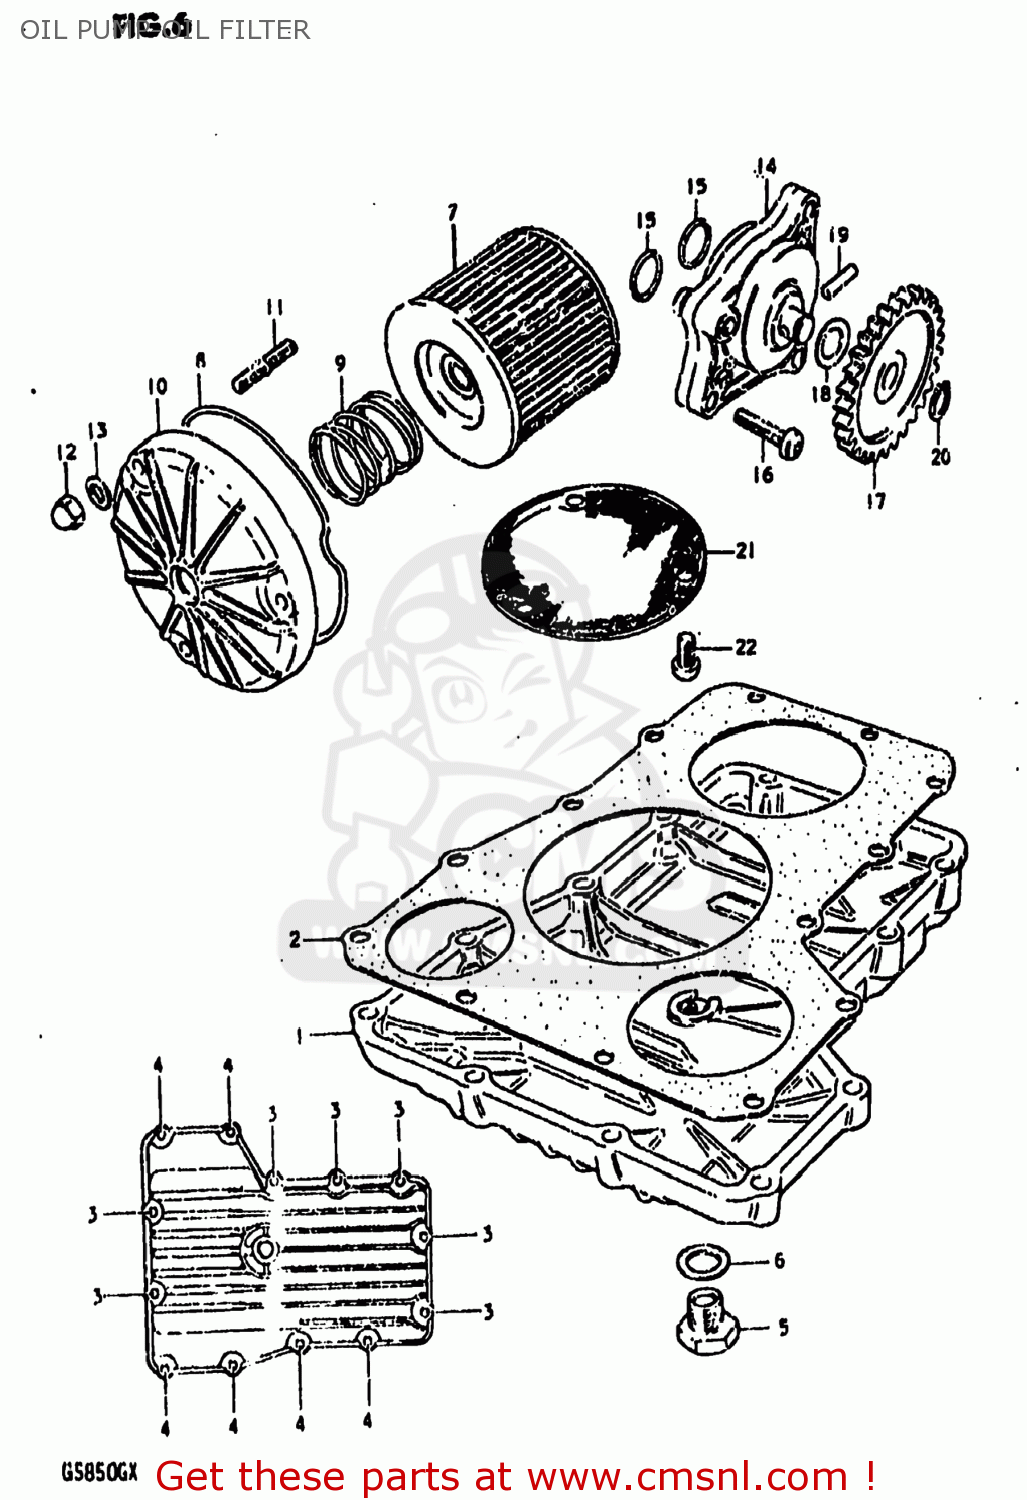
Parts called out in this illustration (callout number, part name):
1	PAN,OIL
2	GASKET,OIL PAN (MCA)
3	BOLT
4	BOLT
5	PLUG
6	GASKET(14X19.2X2) (NAS)
7	FILTER ASSY,ENGINE OIL
8	O RING,OIL FILTER CHAMBER CAP
9	SPRING
10	CAP,OIL FILTER
11	STUD 6X20
12	NUT
13	WASHER
14	PUMP ASSEMBLY,OIL
15	O RING(D:1.9,ID:13)
16	SCREW
17	GEAR,OIL PUMP DRIVEN
18	SHIM
19	PIN(4X15.8)
20	CIRCLIP
21	STRAINER,ENGINE OIL
22	SCREW 6X12
